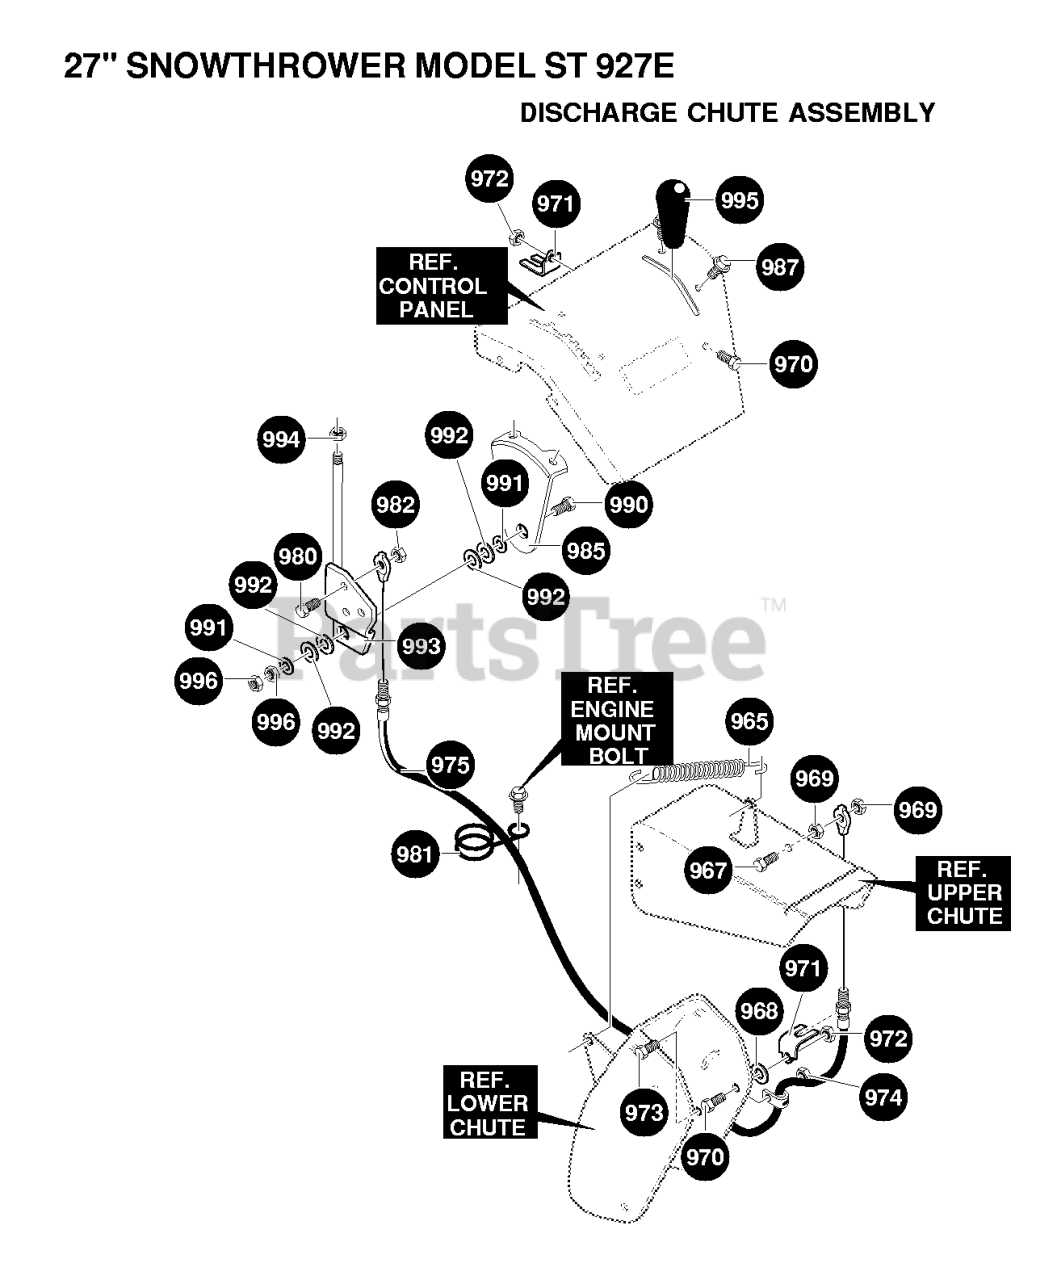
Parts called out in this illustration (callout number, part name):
965	SPRING, TENSION
967	SCREW, 1/4-20X1.00
968	WASHER, FLAT .344X .69X.
969	NUT, 1/4-20 REGHEXCTRLK
970	SCREW, 5/16-18X .75 HHC
971	BRACKET, CABLE CHUTE
972	NUT, 5/16-18 REGHEXCTRLK
973	SCREW, 10-24X.38 SLHWATAP
974	NUT, #10-24 HEXNYLLK
975	CABLE, CHUTE CONTROL 52"
980	SCREW, 1/4-20X .75 HHC
981	WIRE, FORM REMOTE CABLE
982	NUT, 1/4-20 REGHEXCTRLK
985	BRACKET, SP CONTROL
987	SCREW, 5/16-18X .50 WAHHT
990	SCREW, 3/8-16X1.75 HHC
991	WASHER, FLAT .406X .81X.
992	WASHER, SPRING .392X1.05X.082
993	SPEED CONTROL HANDLE
994	NUT, 3/8-16 REGHXCTRLK
995	HANDLE, 3/8-16 MOLDED GRE
996	NUT, 3/8-16 HEXNYL
